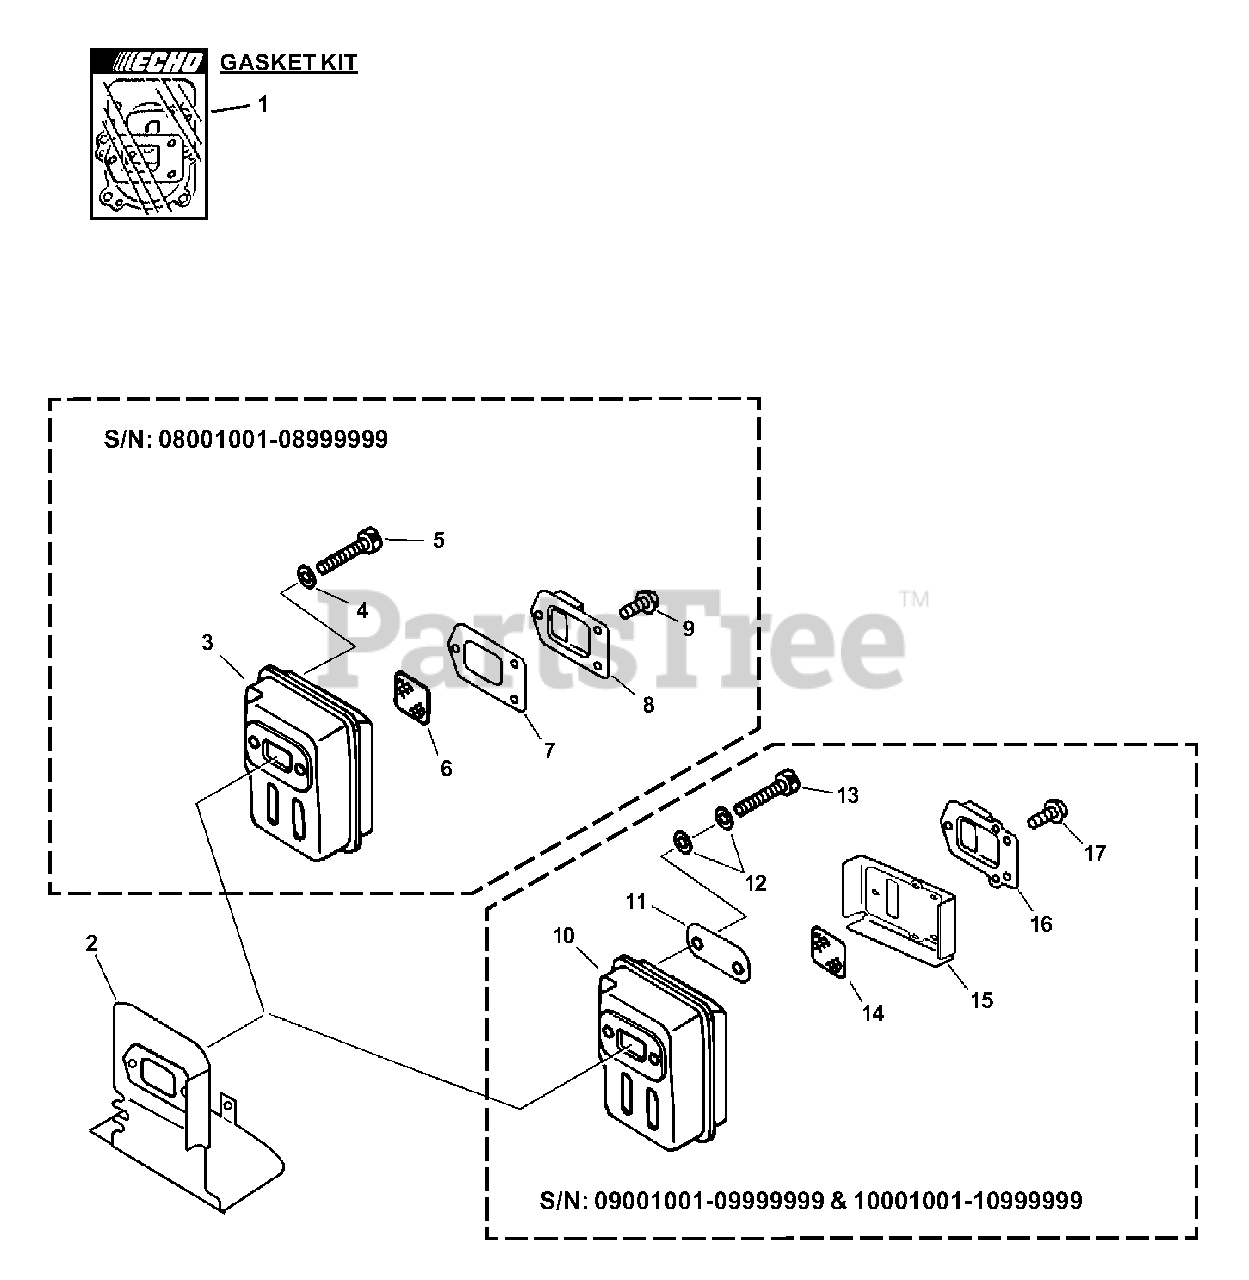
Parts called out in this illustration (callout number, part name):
1	GASKET KIT
2	SHIELD, EXHAUST
4	WASHER - 5
5	SCREW - 5X55
6	SCREEN, SPARK ARRESTOR
7	GASKET, EXHAUST
8	GUIDE, EXHAUST
9	SCREW - 4X10
10	MUFFLER
12	WASHER - CONICAL
13	SCREW - 5X55
14	SCREEN, SPARK ARRESTOR
15	GASKET, EXHAUST
16	GUIDE, EXHAUST
17	SCREW - 4X12
